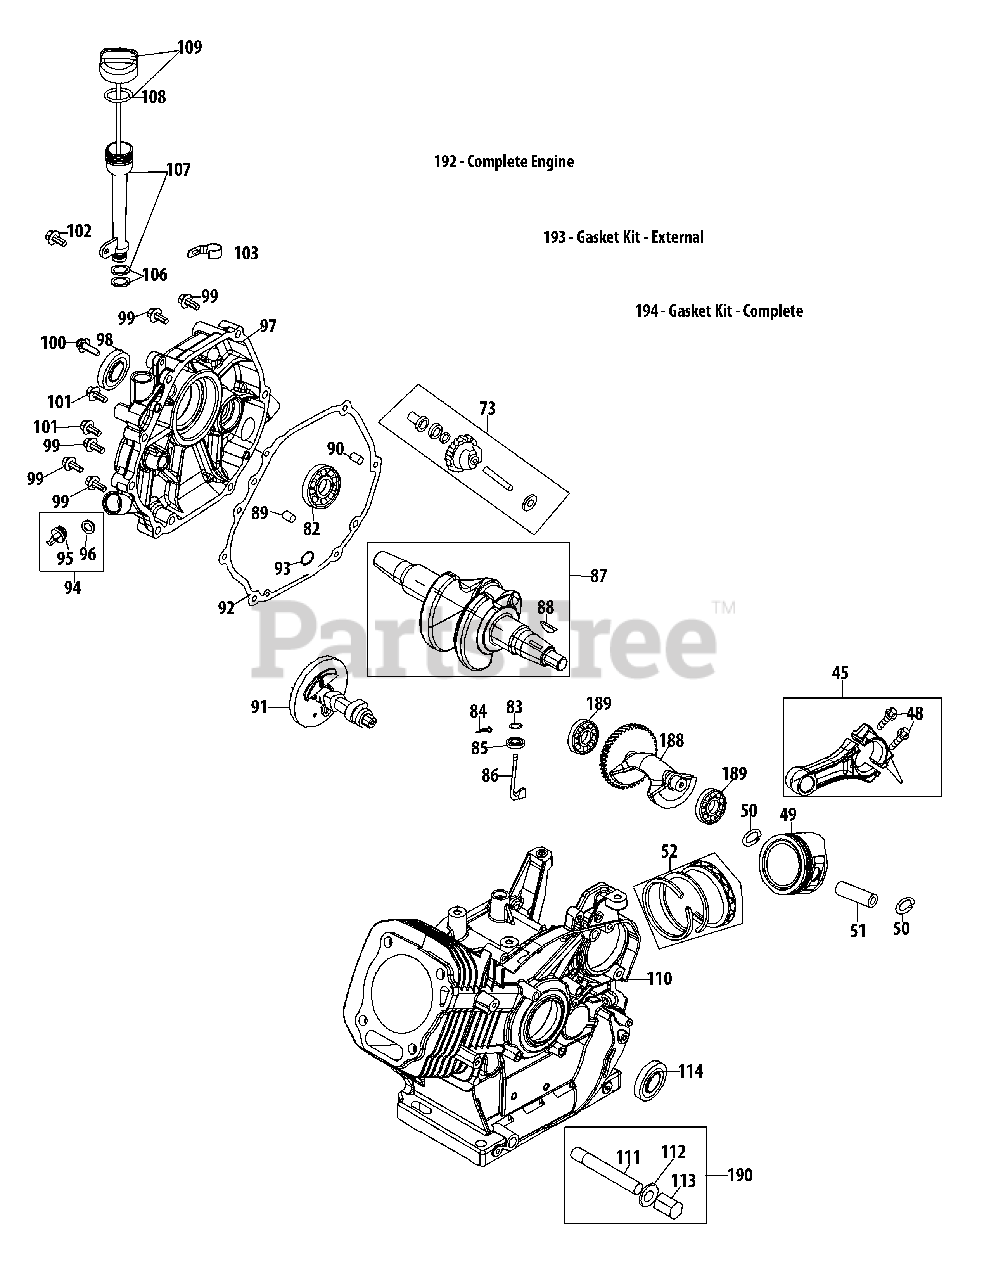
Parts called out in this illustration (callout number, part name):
45	Connecting Rod Assembly
48	Connecting Rod Bolt
50	Piston Pin Snap Ring
51	Piston Pin
52	Piston Ring Set
73	Governor Gear/Shaft Assembly
82	Radial Ball Bearing, 6202-P6
83	Washer 8×20×0.8
84	Cotter Pin
85	Governor Seal
86	Governor Arm Shaft
87	Crankshaft Kit
88	Woodruff Key
89	Dowel Pin 9×12
90	Dowel Pin 7×14
91	Camshaft Assembly
92	Crankcase Cover Gasket
93	Washer 16×24×0.5
94	Oil Fill Plug Assembly
96	O-Ring 16×3
97	Crankcase Cover Kit
98	Oil Seal, 35×52×7
99	Bolt M8×38
100	Bolt M8×45
101	Bolt M8×35
102	Bolt M6×16
103	Dipstick Clamp
106	Oil Fill Tube O-Ring
107	Oil Fill Tube Assembly
108	Dipstick O-Ring
109	Dipstick Assembly
110	Crankcase Kit
110	Short Block
111	Oil Drain Pipe
112	Washer 10×16×1.5
113	Oil Drain Plug
114	Oil Seal 35×52×7
188	Balanceable Shaft Assy.
189	Bearing, 6207-P6
190	Oil Drain Assembly
192	Complete Engine
193	Gasket Kit - External
194	Gasket Kit - Complete
